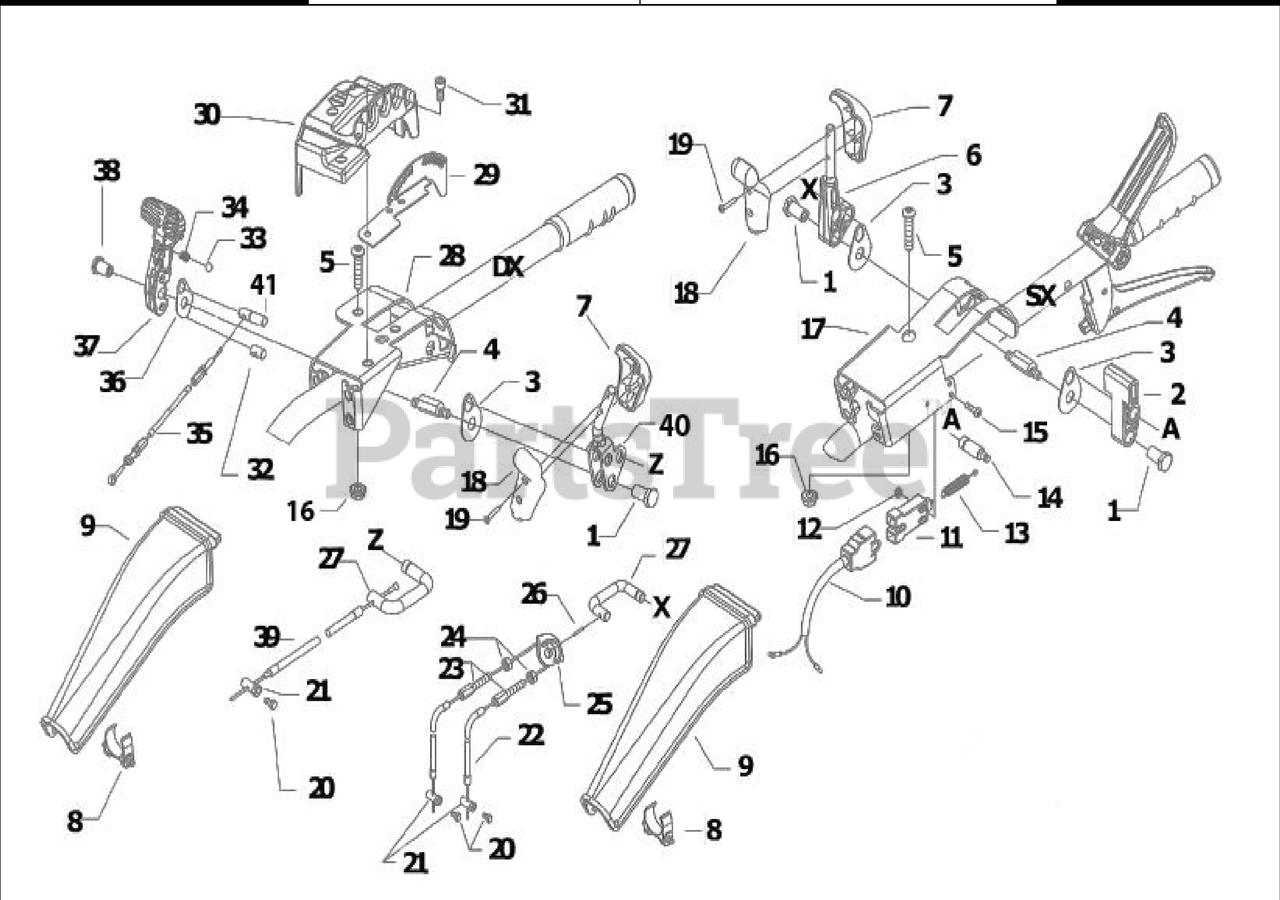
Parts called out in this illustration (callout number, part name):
2	ON/OFF LEVER
3	SMALL PLATE
5	SCREW TBCEI M8X40 ISO7380 10K Z
6	LEVER PARKING BRAKE
8	CROSS MEMBER
9	PROTECTION COVER
10	WIRING
12	SELFLOCK NUT M4 FL.6S
14	INDEXING BOLT
15	SCREW TBCEI FL.M4X25
16	SELFLOCK NUT M8 6S
17	SUPPORT
19	SCREW 3.5X25
20	SCREW TE M6X16 UNI 5739 8G
21	CLAMPING SCREW
22	PARKING BRAKE CABLE
23	ADJUSTING SCREW M8
25	PULLEY
28	SUPPORT
29	SECTOR
30	QUADRANT EASYGRIP
31	SCREW TCEI M8X20 UNI 5931
32	CABLE CLAMP D.12
35	CABLE SPEED / DIRECTION
36	SMALL PLATE
37	LEVER SPEED / DIRECTION
38	STUD BOLT
39	DIFFERENTIAL CABLE
40	LEVER DIFFERENTIAL
41	BARRELL PIN
